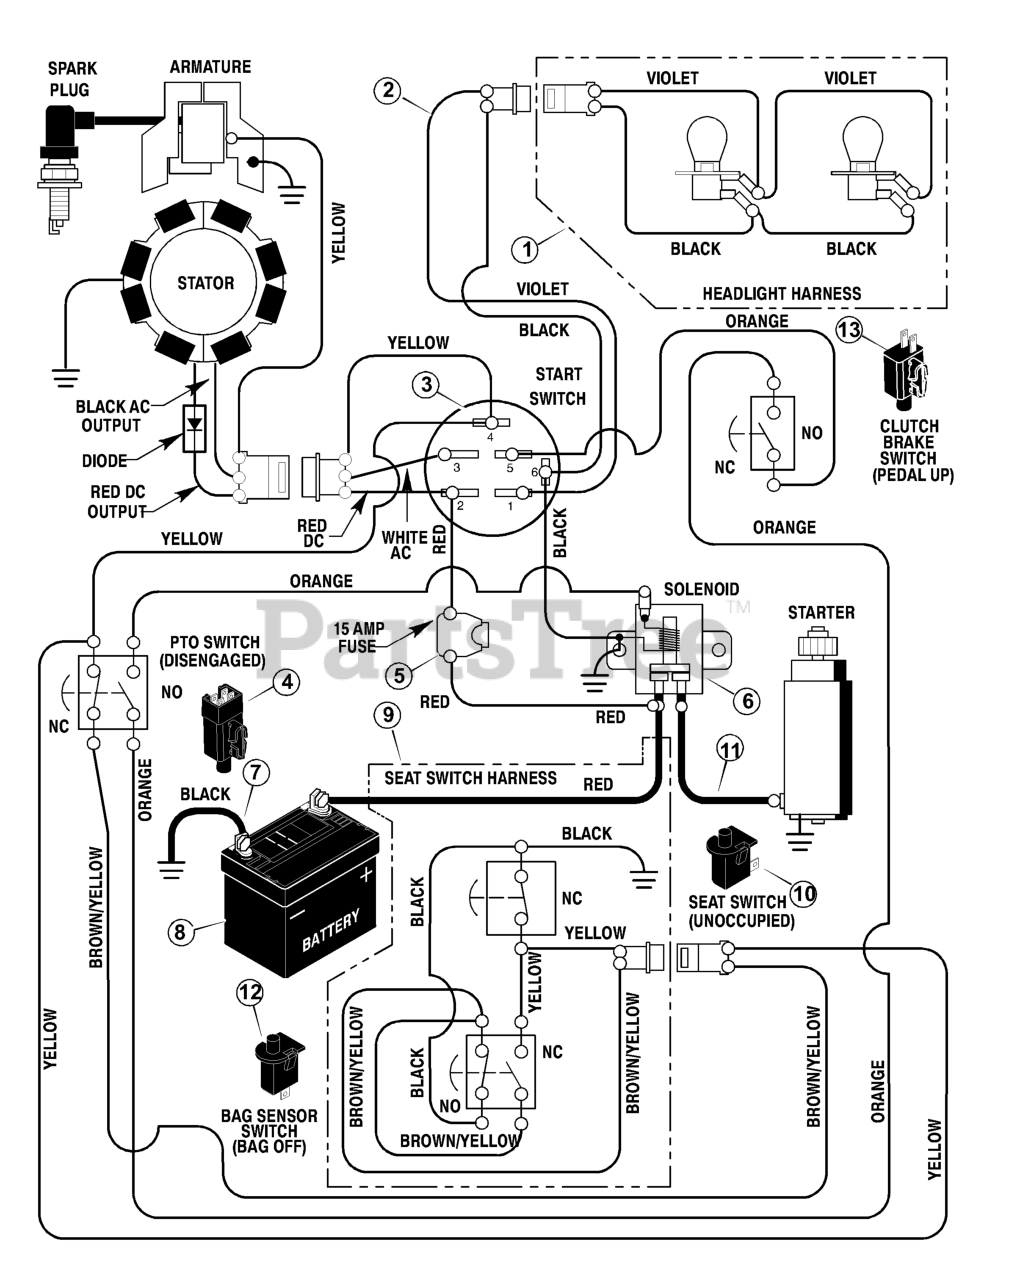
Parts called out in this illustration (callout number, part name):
1	Harness, Light Wire
2	Harness, Chassis Wire
3	Switch, Ignition
4	Switch, Limit
6	Solenoid
7	CABLE, Battery Ground
8	Battery
9	Harness, Seat Switch Wire
10	Switch, Seat Sensor
12	Switch, Bag Sensor
13	Switch, Limit
